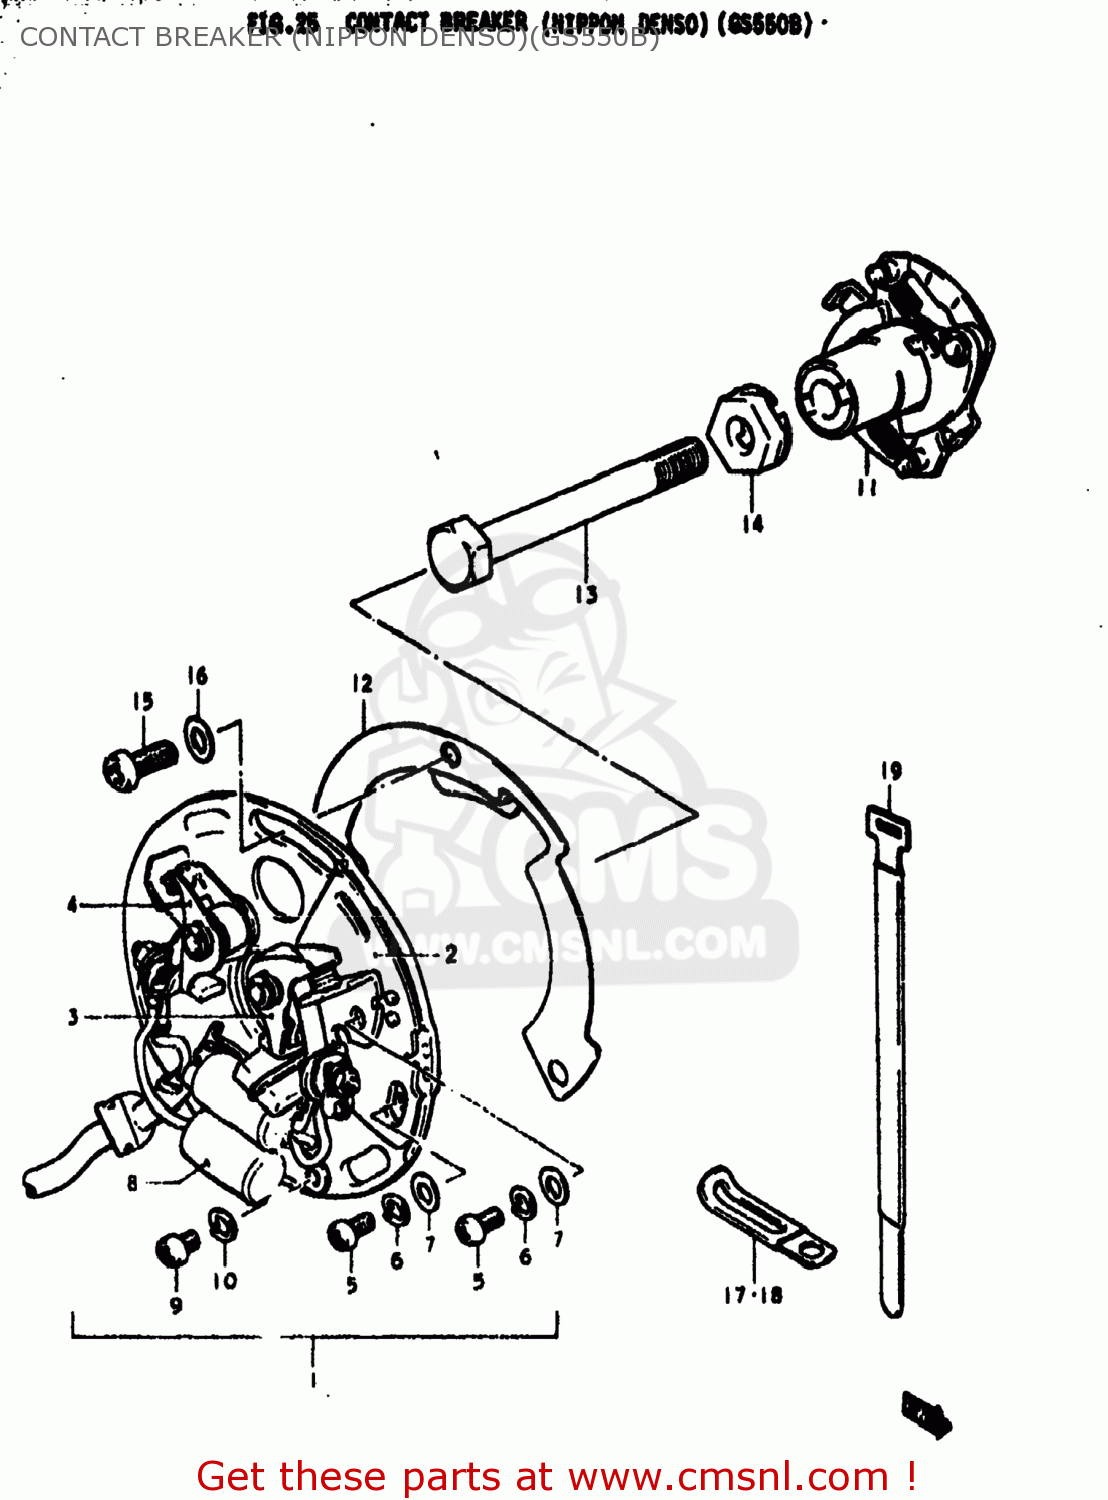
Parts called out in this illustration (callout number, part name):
1	BREAKER ASSEMBLY,CONTACT
2	PLATE,CONTACT POINT
3	POINT ASSY,R
4	POINT ASSY,L
5	SCREW(4X10)
6	LOCK WASHER
7	WASHER
8	CONDENSER
9	SCREW
10	LOCK WASHER
11	GOVERNOR ASSEMBLY
12	PLATE,IGNITION TIMING
13	BOLT
14	WASHER
15	SCREW(5X12)
16	WASHER 5MM
17	CLAMP L:35
18	CLAMP
19	CLAMP
